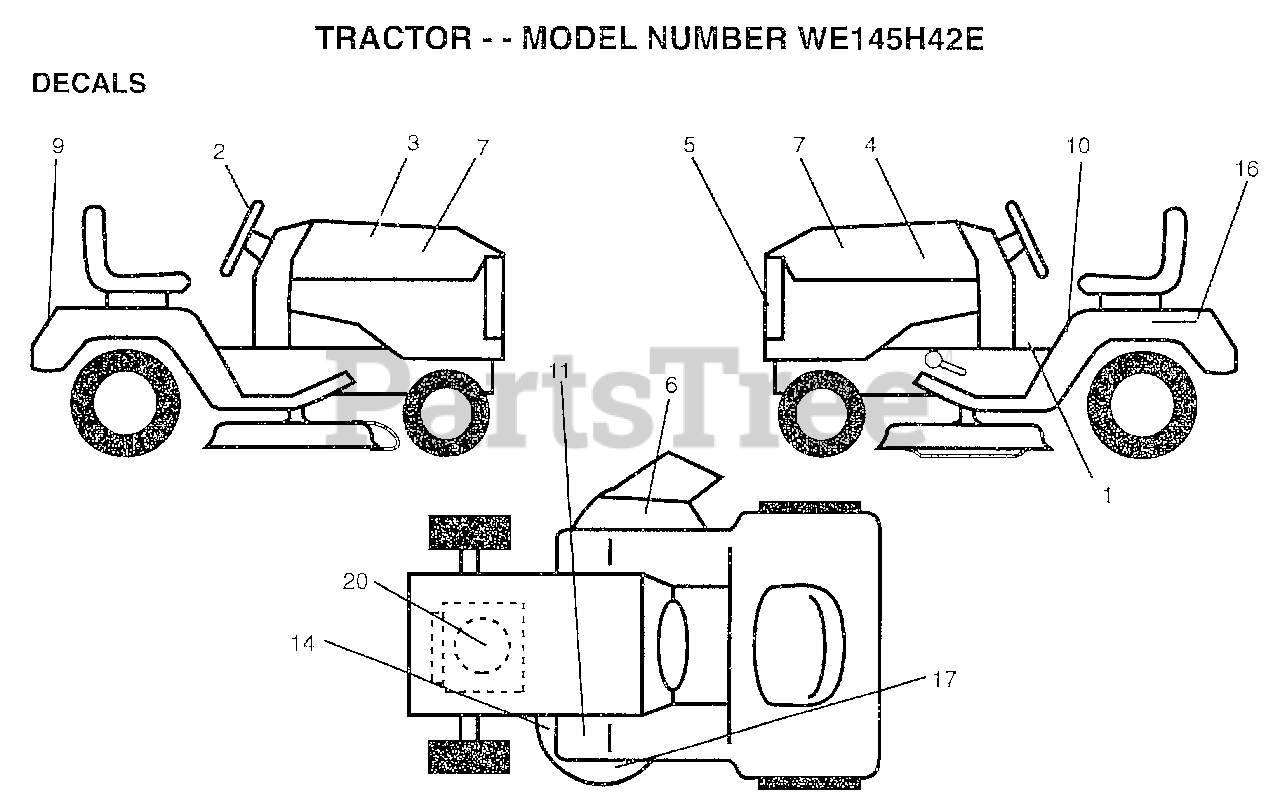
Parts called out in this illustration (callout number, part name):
1	DECAL SADDLE OPER
2	DECAL, INS STRG WH
3	DECAL.HOOD.RH.
4	DECAL.HOOD.LH
5	DECAL, GRILLE LENS
6	"DECAL, WARNING"
7	DECAL.PNL.SD
9	DECAL.FENDER.LOGO
10	DECAL.CAUT.ENG/FR
11	DECAL T
14	"DECAL-SCHEM,BELT"
16	DECAL.BATRY.3-3908
17	DECAL, DECK GRASSEATER
20	DECAL.ENGINE
